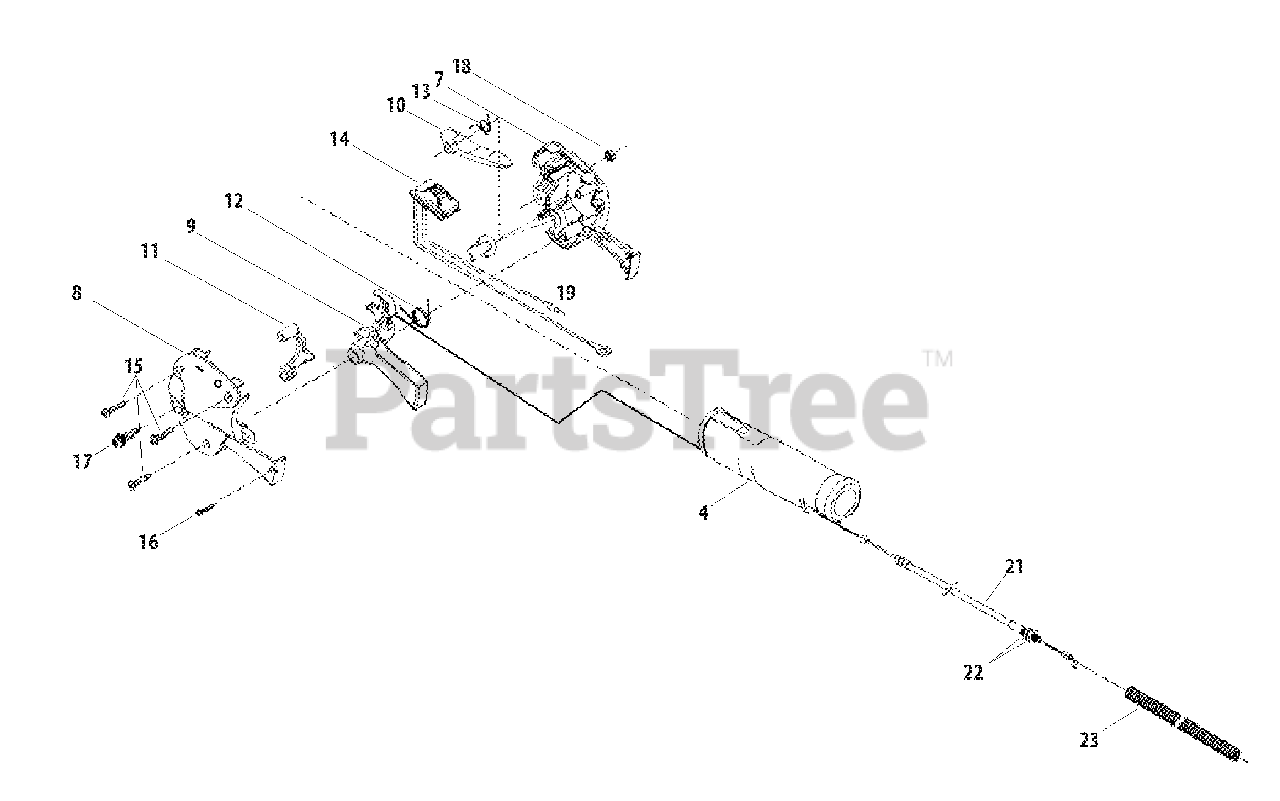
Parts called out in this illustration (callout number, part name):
4	GRIP
7	HANDLE, CONTROL - RIGHT
8	HANDLE, CONTROL - LEFT
9	LEVER
10	LEVER, LOCK
11	HOLDER
12	SPRING
13	SPRING
14	SWITCH, IGNITION
15	SCREW - 4X20 -- TAPPING
16	SCREW - 3X14 -- TAPPING
17	SCREW - 5X20
18	NUT - 5
19	PLUG
21	CABLE, THROTTLE
22	NUT - 6
23	TUBE
